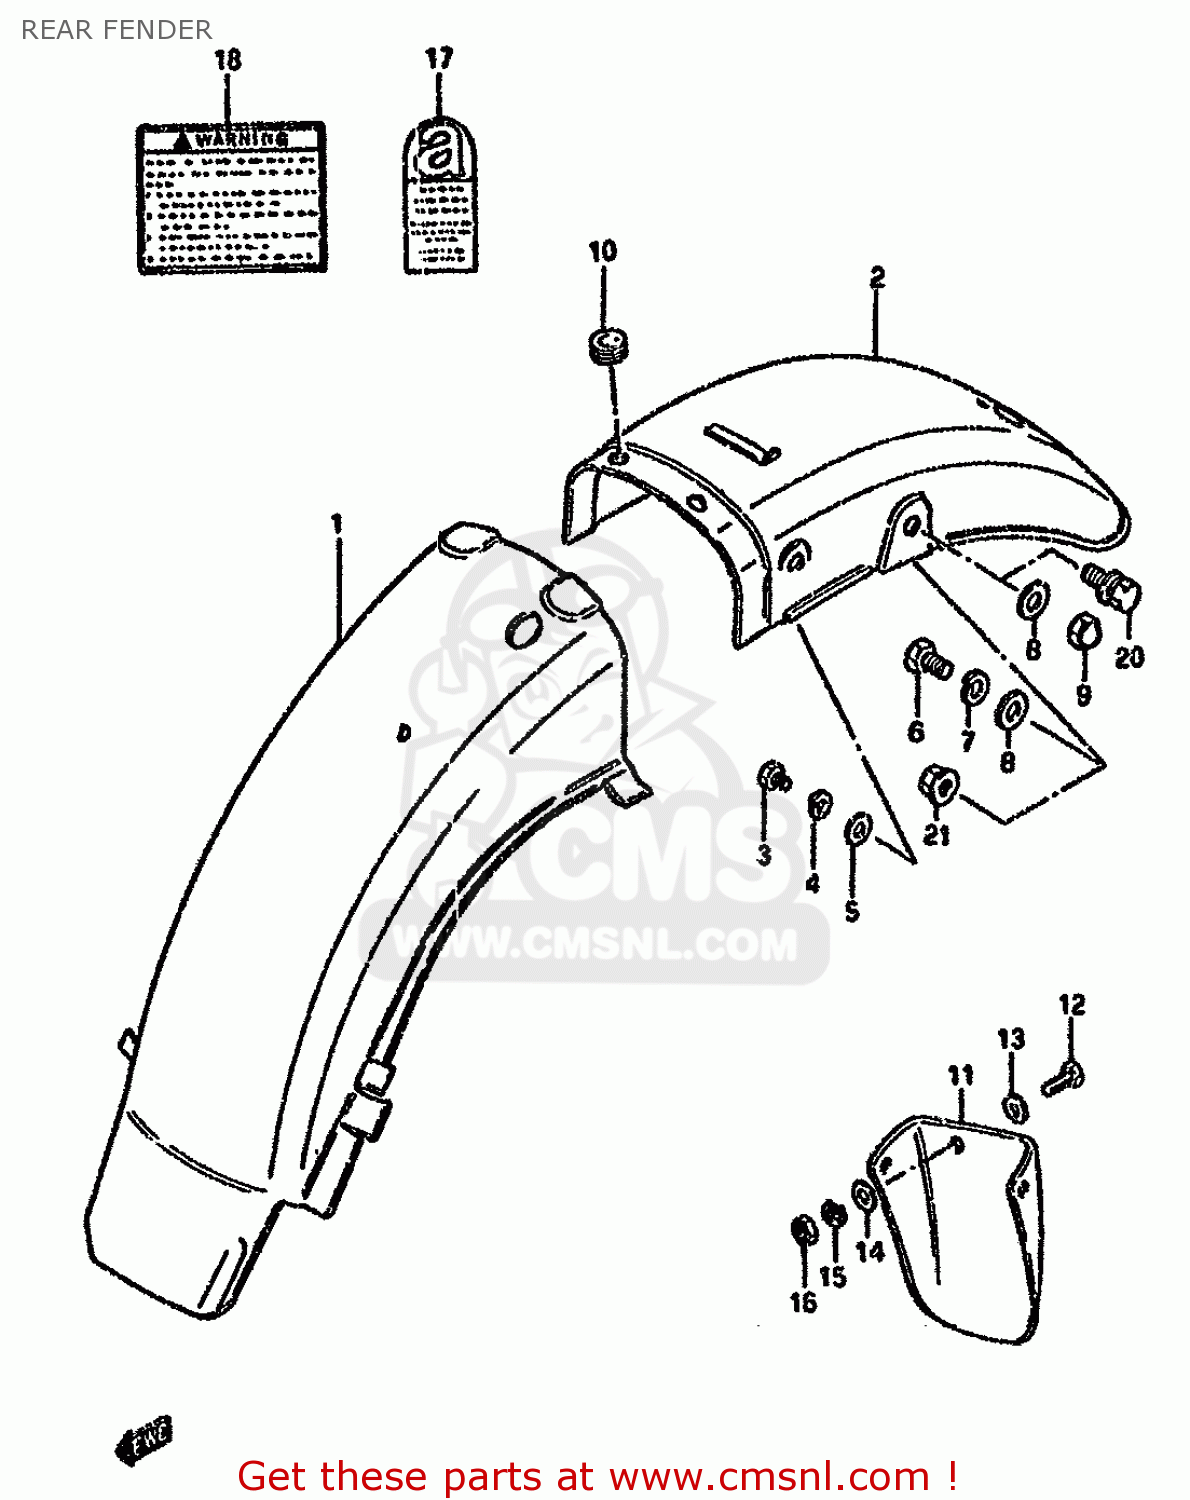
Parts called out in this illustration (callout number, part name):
1	BODY,FR
2	FENDER, REAR
3	BOLT
4	WASHER,LOCK
5	WASHER
6	BOLT
7	LOCK WASHER
8	WASHER
9	NUT
10	CUSHION
11	FLAP,RR FENDER MUD
12	BOLT
13	WASHER
14	WASHER
15	WASHER,LOCK
16	NUT 6MM
17	LABEL,ASBESTOS WARNING
18	LABEL, WARNING SAFETY
19	LABEL (TIRE AIR PRESSURE)
20	BOLT
21	NUT
